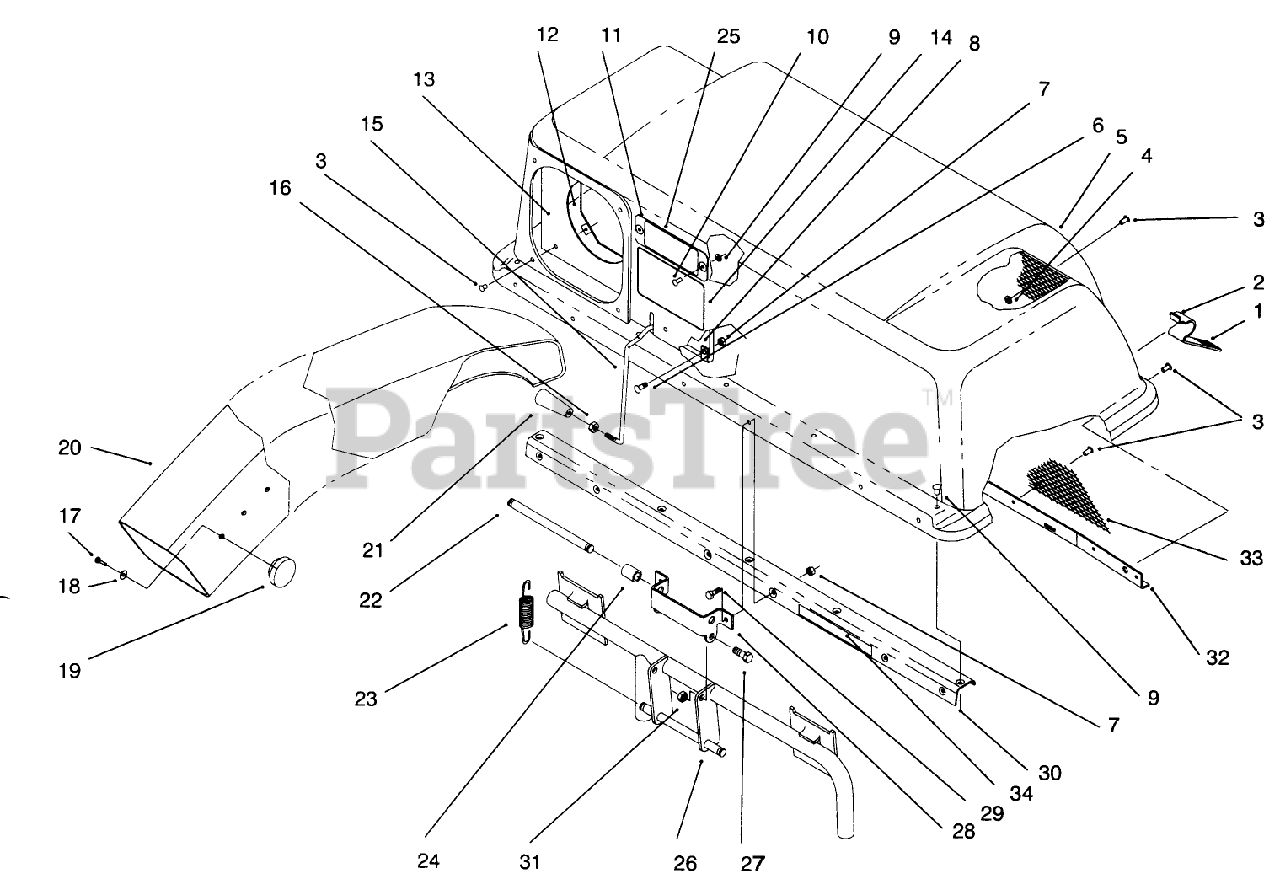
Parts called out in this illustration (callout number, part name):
2	Latch-Bag
3	RIVET-BLIND
4	WASHER-FLAT
5	Bag Top Assembly (Incl. Ref. #9, 10, & 25)
6	SCREW-PPH
7	NUT-LOCK, NI
8	CLAMP
9	WASHER-PLAIN
10	RIVET - POP
11	PLATE-MTG. DECAL B
12	CLAMP-SEAL
13	SEAL-CHUTE
14	DECAL
15	FEELER-FILL, BAG
16	NUT-JAM
17	SCREW-PPHTF
18	WASHER-PLAIN
20	CHUTE-DISCHARGE
21	HANDLE-TAPERED
22	PIN-SPRING
23	SPRING-EXTENSION
24	Spacer
25	DECAL-DANGER
26	FRAME ASM
27	SCREW-HH
28	HINGE-BAG TOPB
29	SCREW-HH
30	Stiffener Assembly (Incl. Ref. #34)
31	NUT-LOCK, NI
32	Screen Support
33	SCREEN-BAGGER
34	DECAL-CAUTION
